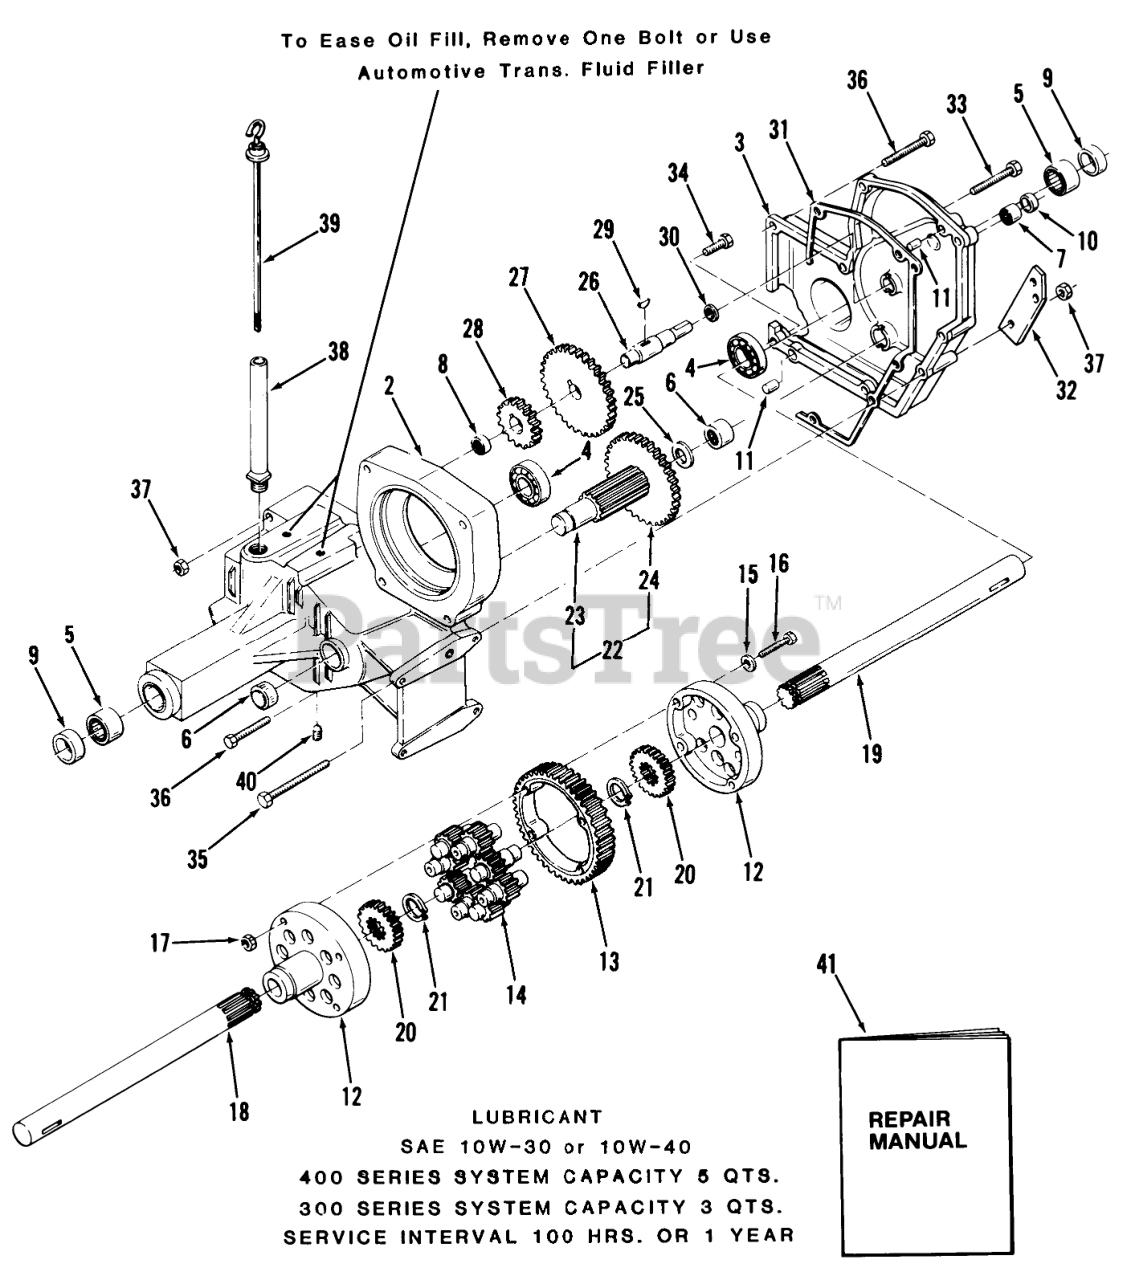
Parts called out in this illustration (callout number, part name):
5	BEARING
6	BEARING-NEEDLE
7	NEEDLE BEARING
8	BEARING-NEEDLE
9	SEAL-OIL
11	PIN-LOCATING
12	DIFFERENTIAL END CAP
13	GEAR-DIFFERENTIAL RING, 43T
14	GEAR-PINION, 11T
15	WASHER
17	NUT-HEX
20	GEAR-AXLE DIFFERENTIAL
21	RING-SNAP
22	GEAR ASM
23	PINION SHAFT
25	WASHER-THRUST
26	SHAFT GEAR
27	GEAR 46 TEETH
31	GASKET-TRANSMISSION
38	NIPPLE-TRANS FILL
41	Repair Manual
